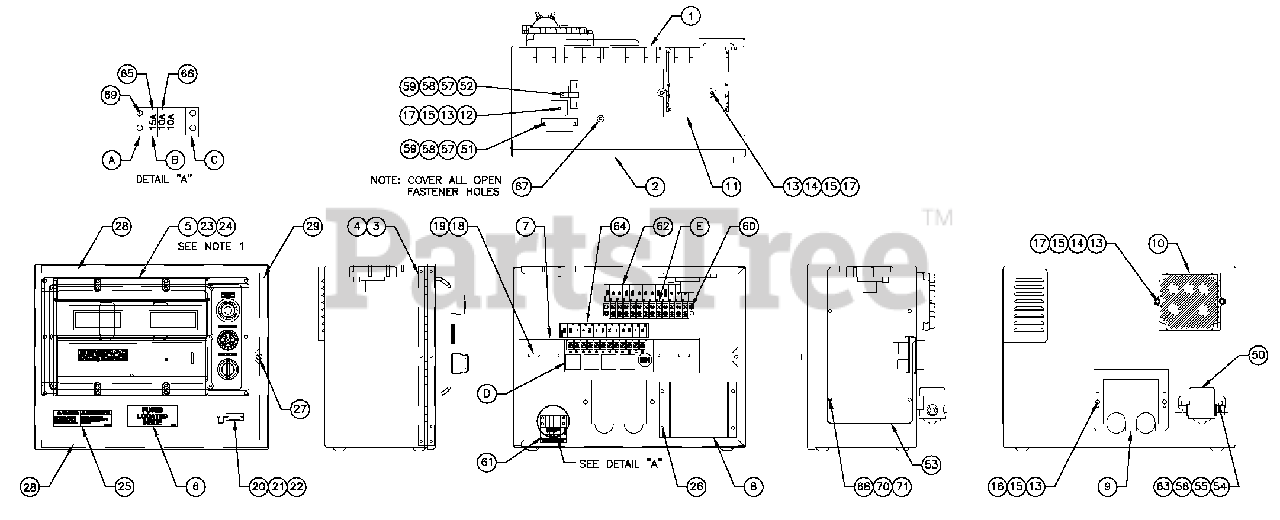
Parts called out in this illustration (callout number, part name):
1	ENCL H/G CONTROL PANEL
2	COVER CONTROL PANEL
3	HINGE CONTINUOUS H PANEL
4	RIVET POP .125 X .275 SS
5	ASSY PROGRAMMED H-100
6	DECAL FUSES LOCATED INSIDE
7	RAIL SNAPTRACK PCB HOLDER BULK (12"LG)
8	ASSY PCB 2AMP 12V UL BATT CHGR
9	PLATE HARNESS CLAMP
10	ASSY PCB PWR AVR W/AMP HEADER
11	ASSY PCB BOSCH GOV DRIVER
12	DIO BRIDGE 25A 600V
13	WASHER LOCK M5
14	SCREW PPHM M5-0.8 X 30 SS
15	WASHER FLAT M5
16	SCREW HHPM M5-0.8X 12
17	NUT HEX M5-0.8 G8 YEL CHR
18	WASHER FLAT M4
19	SCREW PHTT M4-0.7 X 10 ZYC
20	CONN DUST CAP W/CHAIN DB9
21	WASHER FLAT M3.5
22	SCREW PHTT M3.5-0.6X 10
23	SCREW PPHM M4-0.7 X 8 BLX OX
24	WASHER LOCK #8-M4
25	DECAL WRN BATT CHRG 12/24V BI
26	SCREW PHTT M4-0.7 X 12 ZYC
27	M5-0.8 CAPTIVE PANEL KNLD HD
28	SEAL COVER 3.18X12.7X382
29	SEAL COVER 3.18X12.7X283
50	RELAY CONTACTOR 12VDC
53	COVER CONTROL PANEL SIDE
54	SCREW HHC 1/4-20 X 3/4 G5
55	WASHER FLAT M6-1/4
56	WASHER LOCK M6-1/4
57	WASHER LOCK M3
58	NUT HEX M3-0.5 G8YEL CHR
59	WASHER FLAT M3
60	SCREW PHTT #6-32 X 5/8 ZYC
61	DECAL CPL CONTROL PANEL FUSES
62	DECAL CPL 5.4/6.8L TB3
63	NUT HEX 1/4-20 STEEL
64	DECAL CPL 5.4/6.8L RELAY BOARD
65	FUSE ATO TYPE 15 AMP (BLUE)
66	FUSE ATO TYPE 10 AMP (RED)
67	SEAL WEATHER .45"DIA
68	SCREW PPHM M5-0.8 X 12 ZNC
69	SCREW PHTT #6-32 X 3/8 ZYC
70	WASHER FLAT M5
71	WASHER LOCK M5
A	ADPTRRH SIDE WICKMANN 178.6191
B	HOLDER FUSE WICKMANN 178.6150
C	ADPTR LH SIDE WICKMANN 178.6192
D	ASSY PCB G-PANEL RELAY 12VDC
E	BLOCK TERM 20A12 X 6 X1100V
